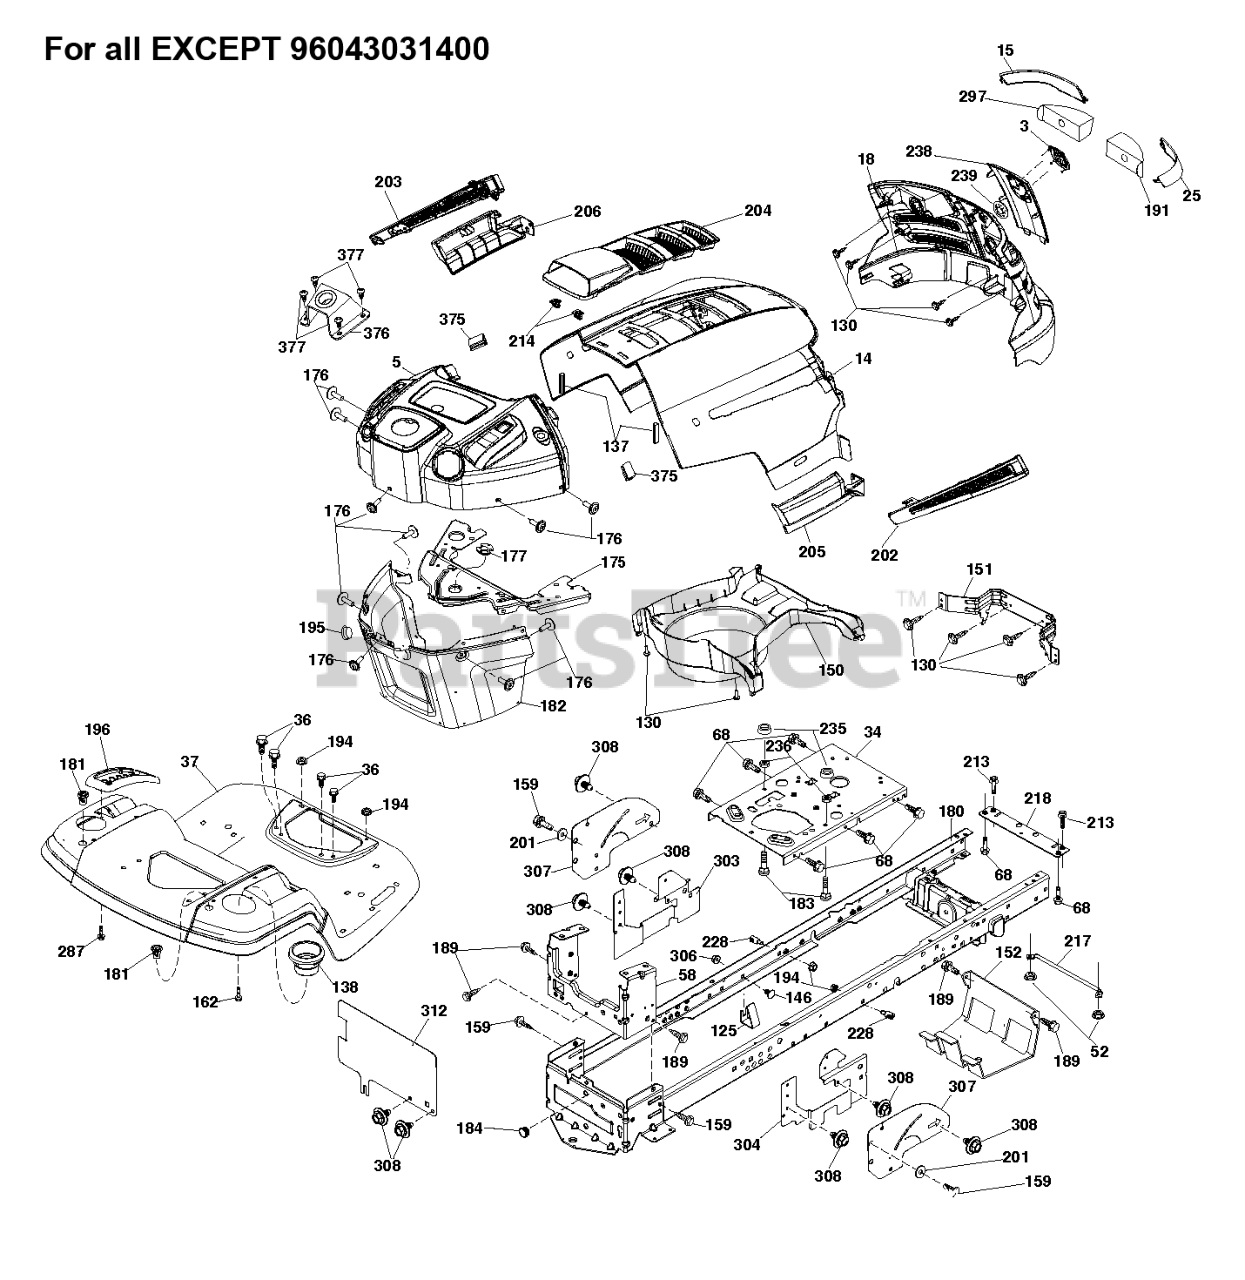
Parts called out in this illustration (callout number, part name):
3	LOGO.HUSQ.GT.LT.CROWN.H
5	SUBASM.DASH.UPPER.W/BUMPER
5	DASH.UP.HU.LT.CBL.CLTCH.CHG.PT
5	SUBASM.DASH.UPPER.HLT.498
5	DASH.UPPER.HUS.LT.CABLE.CLUTCH
14	HOOD.HUSQVARNA.LT.ORANGE
15	LENS.HUSQVARNA LT.RH
18	ASM.GRILLE HUSQVARNA.LT.498
18	GRILLE.SVC.HUSQVARNA.GREY
25	LENS.HUSQVARNA LT.RH
34	PLATE.ENGINE.WELDED.CHASSIS
36	SCREW 5/16"
37	FENDER.TLT.PDL.CNTRL.W/CPH.ORG
58	DRAWBAR UPPER 2PC SMALL FENDER
68	Screws
68	SCR 5/16-18 X 1/2 SELFTAP ZN
68	Screw 5/16-18 x 1/2 Hex, Self Tapping 5/16-18 x 1/2
125	CLIP.FUEL.LINE
130	Screws
130	SCREW.#10 X 0.750.BOS
137	BUMPER DASH
138	HOLDER.CUP.LT.GREY
146	BOLT.RDHD.SHT.SQNK.3/8-16X5/8
150	DUCT.AIR.
150	AIR DUCT
151	BRACKET PIVOT
152	SHIELD.BROWNING.W/TEX
159	SCREW, 3/8-16X3/4
175	CROSSMEMBER
176	SCREW.#10-24X5/8.RN.QU
177	BUSHING STEERING
180	CHASS.WLDMNT.TL.12GA/2P.48/54
181	BUSHING.MNT.FEND.CRGO.
181	BUSHING.MNT.FEND.CRGO.TEX.49
182	DASH.LOWER.PREDATOR LT
184	PLUG.DEMO.625
189	SCREW
191	INSERT.REFLECTIVE.RH.
195	PLUG.TEX.DASH.SVC.MINDER.GREY
196	DECKLFT.CONSOL FULL ASSM GREY
201	WASHER
202	VENT.SIDE.HUSQVARNA.LT.RT
203	VENT.SIDE.HUSQVARNA.LT.LFT
204	SUBASM.TOP.VENT.HUSQ.LT
205	SKIRT.SIDE.HUSQVARNA.LT.RT
206	SKIRT.SIDE.HUSQVARNA.LT.LEFT
213	SCREW HEXAGON HEAD SCREW 5/16-
213	HCS 5/16C X 3/4
214	CLIP.RETAINER.TINNER.
217	ROD.PIVOT.HOOD
218	X-PIECE.HOOD.STOP.NON/
228	STUD.W/"D"ANTI-ROTATION
235	Spacers
235	SPACER FENDER
236	NUT.CENTERLOCK.5/16-
238	TRIM.HUSQ LT.668
287	SCREW 1/4X20
297	INSERT REFLECTIVE
303	SHIELD.LWR.LH.LTGT.NON30
303	SHIELD.LOWER.LH/LT/GT/BLK.EDIP
304	SHIELD.LWR.RH.LTGT.NON30.NOTCH
304	SHIELD.RH.LOW.LT/GT.NON-30.PNT
306	NUT LOCK FLG 3/8-16 UNC
307	SHIELD.UPPER.LT.GT.ISO
308	BOLT.5/16-18UNCX3/4 W/SEMS.BLK
312	COVER DRBAR.LT.FRTTANK.ISO X43
375	BUMPER CLIP-ON. DASH 1"
376	MOUNT.ASM.HUSLT.UPPER.STRNG
377	SCREW 10 X 1/2 ZN PL PHIL PAN
